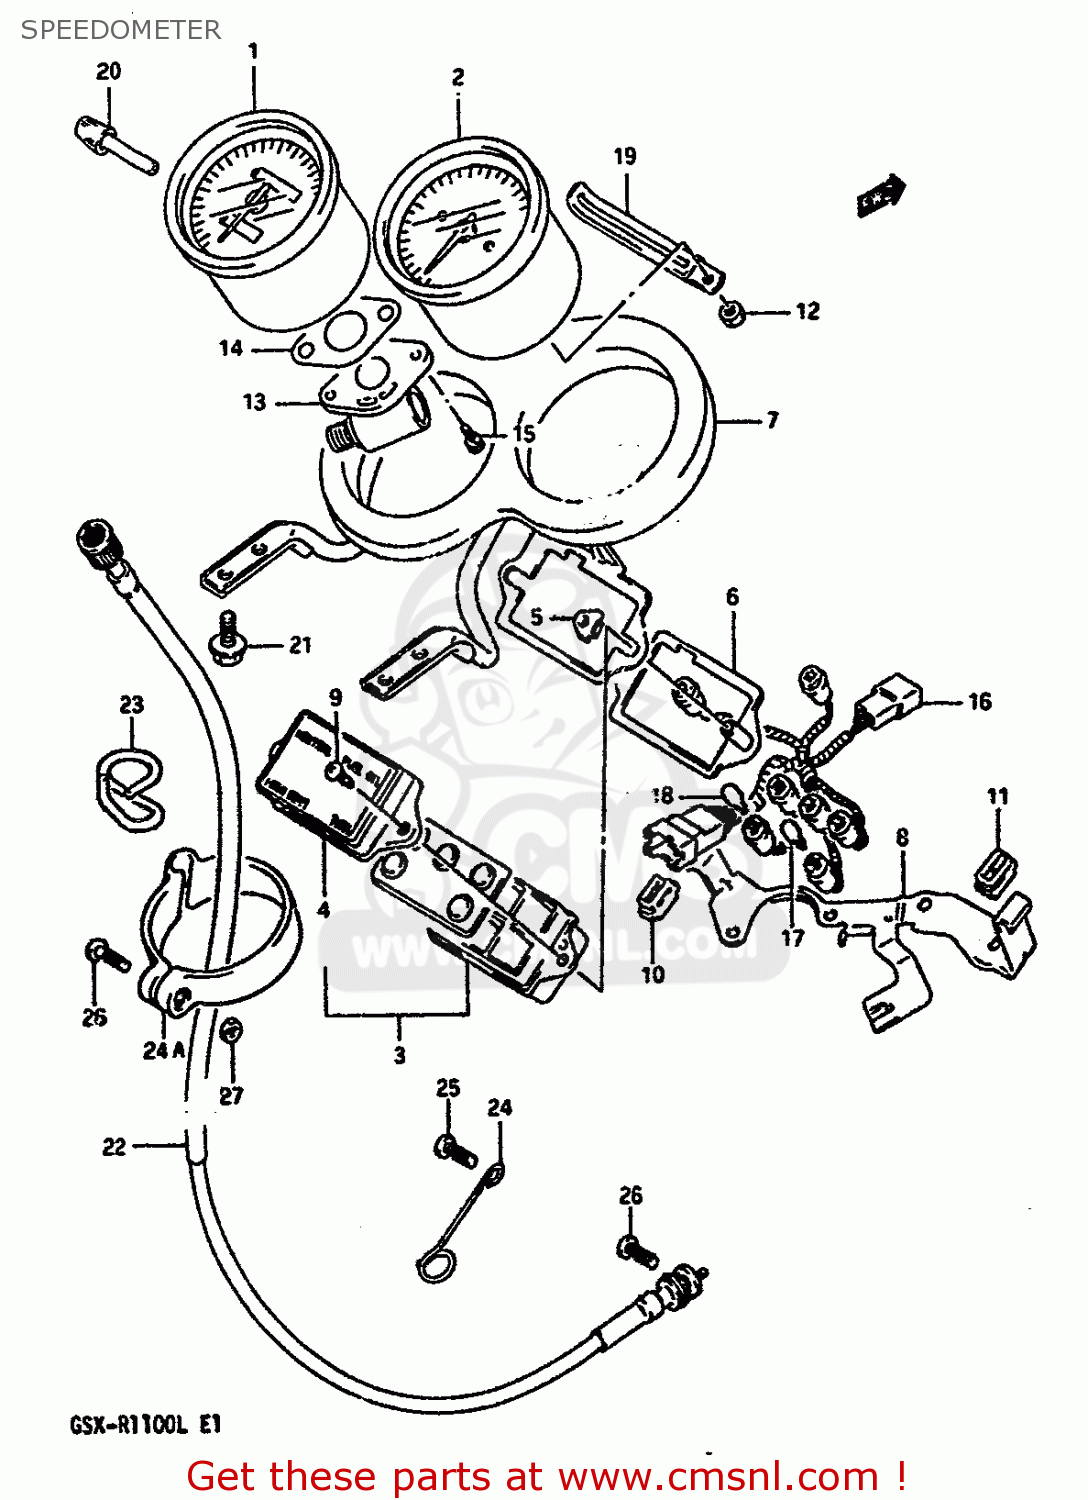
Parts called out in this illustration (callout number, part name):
1	SPEEDOMETER
2	TACHOMETER
3	BOX ASSEMBLY,PILOT LAMP
4	LENS,BOX
5	DAMPER
6	PLATE,SETTING
7	PLATE,SETTING
8	BRACKET
9	SCREW
10	DAMPER,LEFT
11	CUSHION
12	NUT
13	GEAR BOX
14	GASKET,METER GEAR BOX (NAS)
15	SCREW
16	SOCKET,METER
17	BULB(12V3W,T6.5)
18	BULB(12V1.7W,T6.5)
19	CLAMP
20	KNOB,TRIP
21	BOLT 6X12
22	CABLE ASSEMBLY,SPEEDOMETER
23	GUIDE,SPEEDOMETER CABLE
24	GUIDE,SPEEDOMETER CABLE,R
24A	GUIDE,METER CABLE NO.2
25	SCREW
26	SCREW
27	NUT
